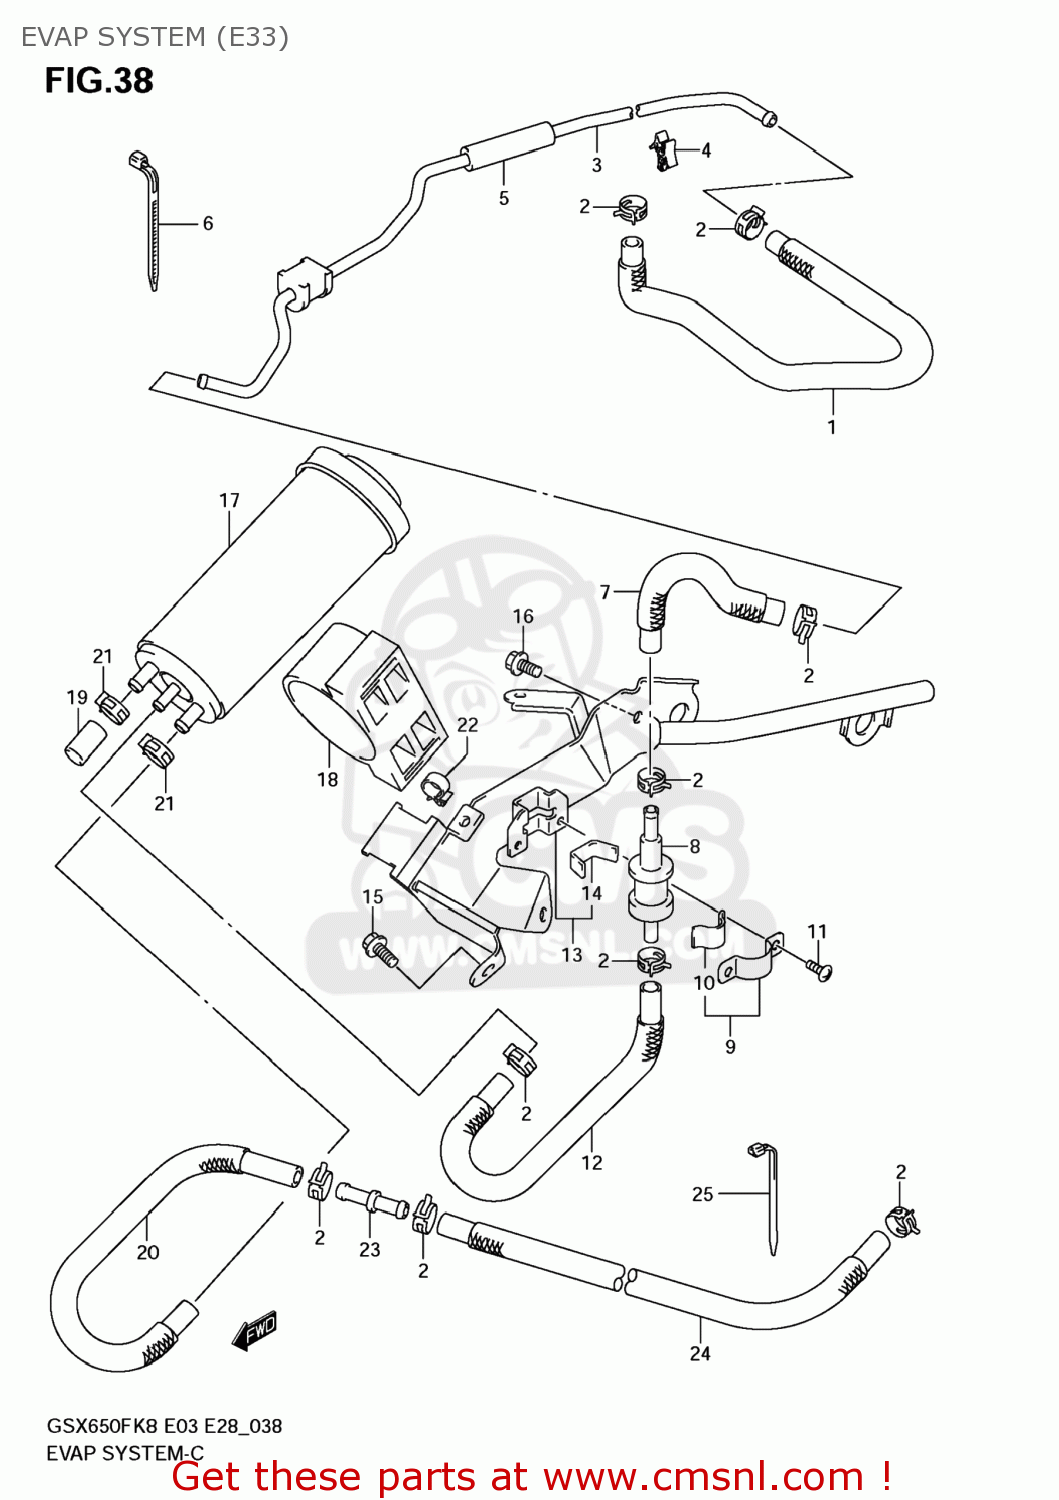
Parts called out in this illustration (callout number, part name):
1	HOSE,TANK & BREATHER VALVE
2	CLIP
3	PIPE,TANK & BREATHER
4	CLAMP
5	CUSHION,FR FENDER SIDE
6	CLAMP(L:95)
7	HOSE,TANK & BRTHR VALVE NO.2
8	VALVE,FUEL TANK BREATHER
9	PLATE,FUEL TANK BREATHER NO.2
10	CUSHION
11	SCREW
12	HOSE,CSTR & BREATHER VALVE
13	BRACKET COMP,CA
14	CUSHION
15	BOLT
16	BOLT
17	CANISTER SET
18	CUSHION,CANISTER
19	CAP,OD:11.5
20	HOSE,CSTR & PURGE VALVE
21	CLIP
22	CLAMP
23	JOINT
24	HOSE,CSTR & PURGE VALVE NO.2
25	CLAMP(L:125)
